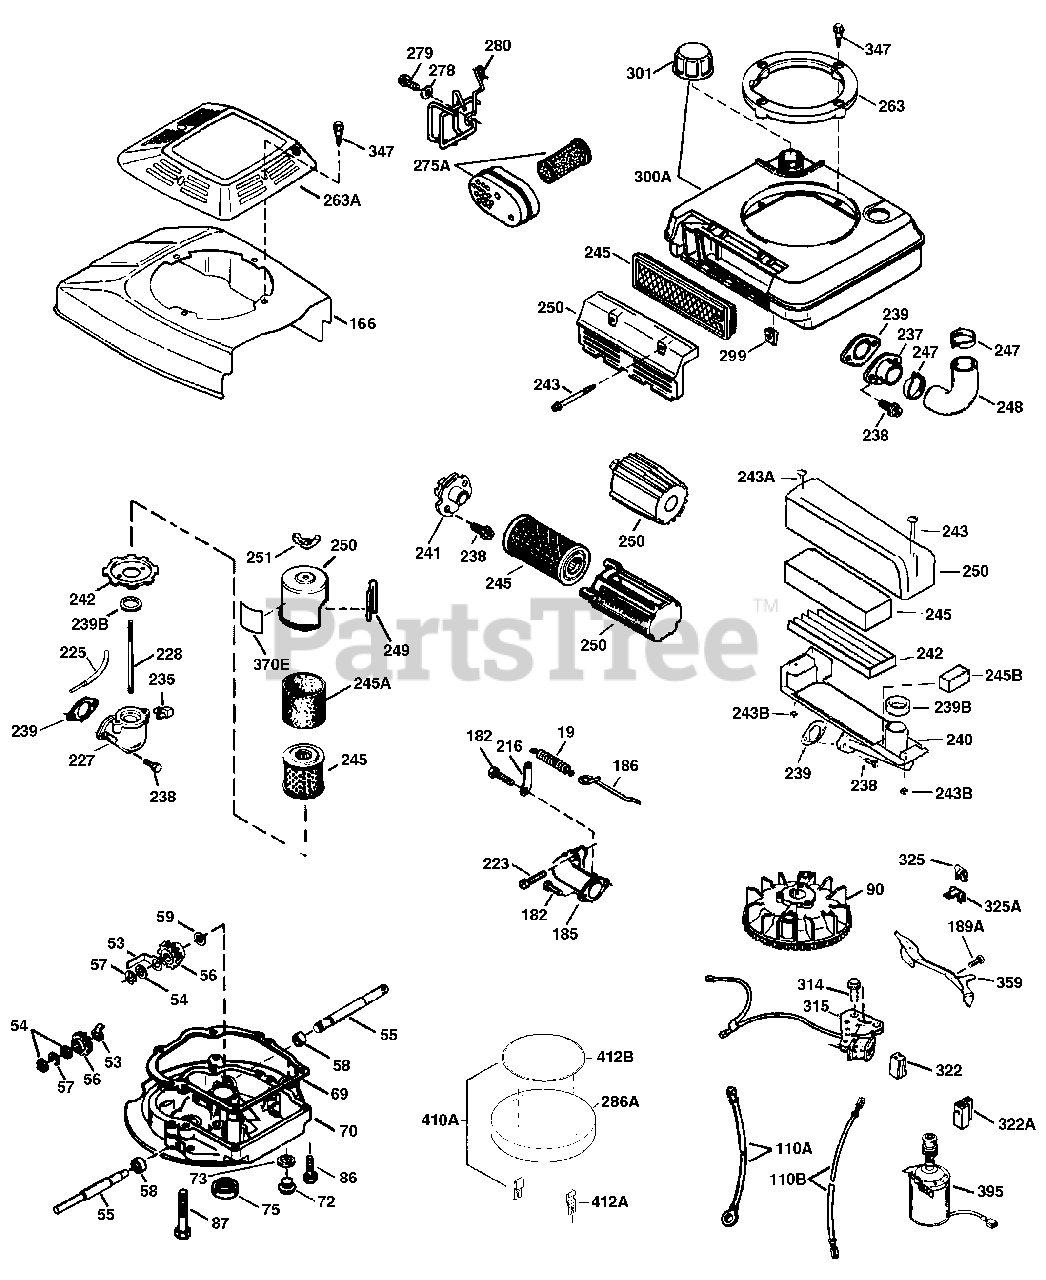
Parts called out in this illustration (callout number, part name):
19	Extension Spring
69	* Mounting Flange Gasket
70	Mounting Flange (Incl. 72 thru 83)
72	Oil Drain Plug
73	Drain Plug Gasket
75	Oil Seal
86	Screw, 1/4-20 x 1-1/4"
90	Flywheel
182	Screw, 1/4-28 x 7/8"
185	Intake Pipe
186	Governor Link
223	Screw, 1/4-20 x 1"
238	Screw, 10-32 x 49/64"
239	* Air Cleaner Gasket
241	Air Filter Collar
245	Air Filter (Paper) (also available in Packaged Part #740095 (Qty.2))
250	Air Filter Cover (Craftsman)
275A	Spark Arrestor Muffler (Optional) (In cl. 284,284A,416,417)
284	Muffler Deflector (Incl. 284A) Option al
284A	Screw, 8-32 x 3/8" (Optional)
301	Fuel Cap
999	Summer Maintenance Kit (incl. Oil, Sp ark Plug, Air Cleaners (2), & Ultra-F resh)
